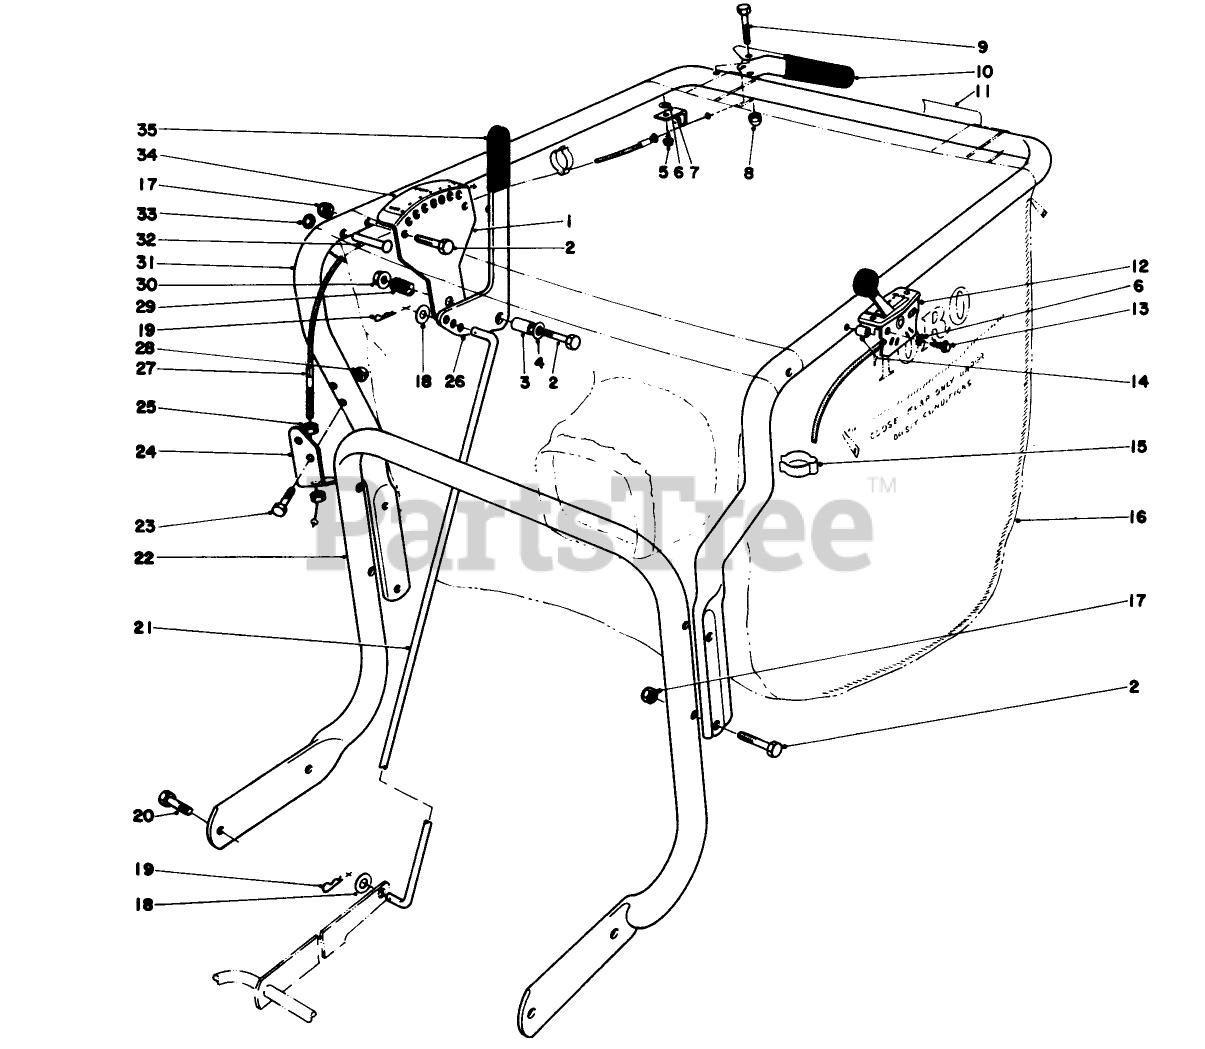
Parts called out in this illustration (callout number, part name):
2	SCREW-HH
3	SPACER
4	WASHER-FLAT
5	SCREW
6	WASHER-LOCK, EXT
7	RETAINING-CLIP
8	NUT-CAP
9	SCREW-HH
10	LEVER W/GRIP
14	SPACER
17	NUT-LOCK, CONE
18	WASHER-FLAT
19	PIN-COTTER
20	Screw
21	HEIGHT ADJ. ROD
22	HANDLE
23	SCREW-HH
24	MOUNT-BOWDEN, LOWER
27	FWD ASSY CABLE
28	NUT-LOCK, CONE
29	SPRING-COMPRESSION
30	NUT-HF
31	HANDLE-UPPER, VACUUM
32	RIVET
33	RING-RETAIN,PUSH,EXT,FLAT
35	GRIP-HANDLE
